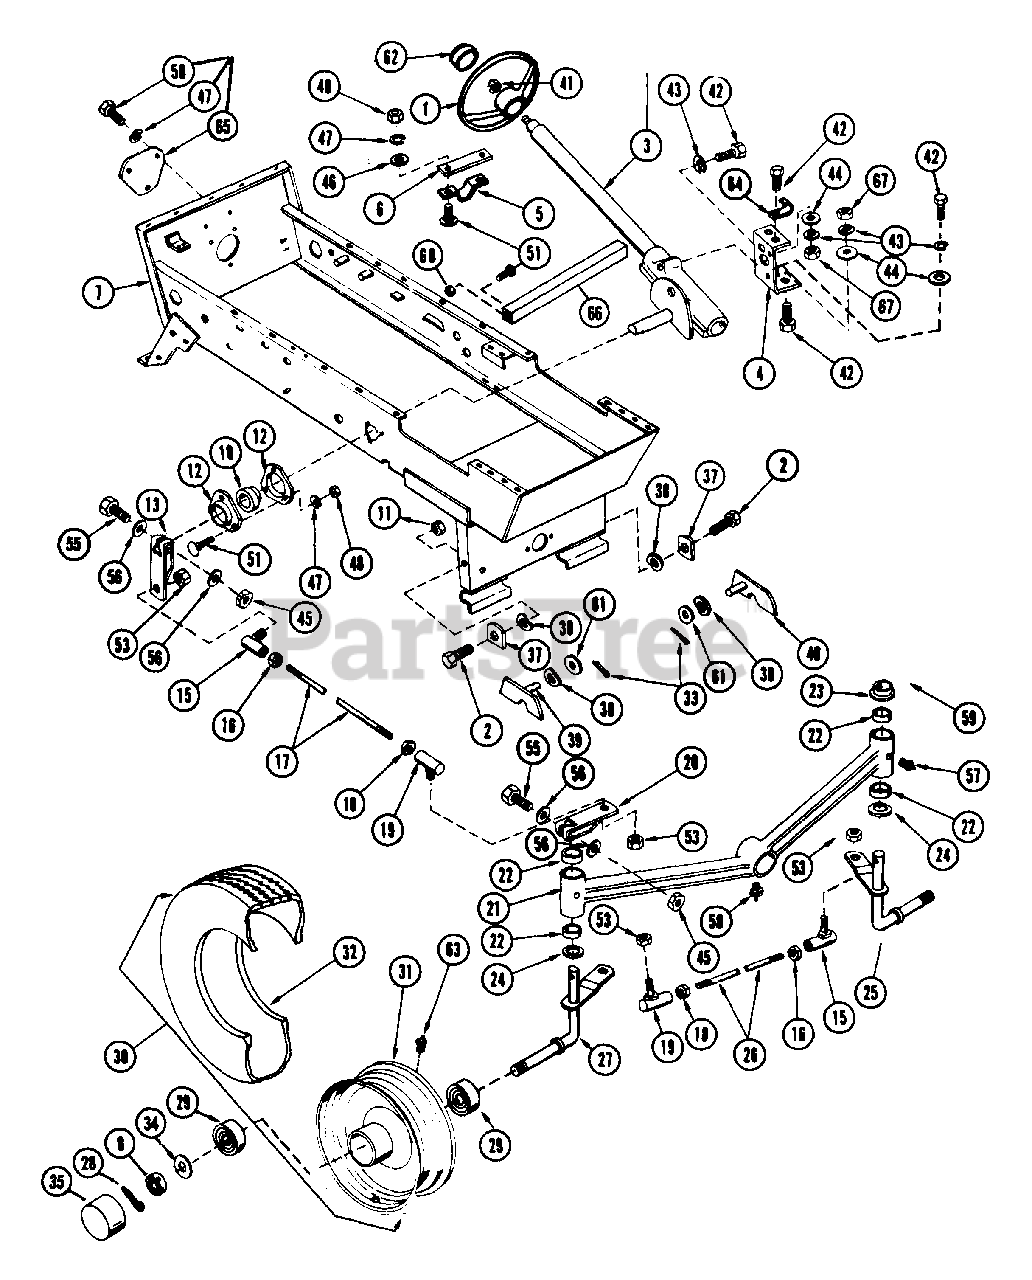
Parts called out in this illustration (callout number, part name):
1	STEERING WHEEL
2	BLT-HEX .38-16X1.00 PL
3	STEERING GEAR ASSY
4	MOUNTING BRACKET
5	STEERING COLUMN CLAMP
7	MAIN FRAME ASSY HYDRO
7	MAIN FRAME ASSEMBLY - TWIN
7	MAIN FRAME ASSY 10G
7	MAIN FRAME ASSY 14G
8	NUT-SL 1.0-14
10	BRG-BALL 1.0X2.047X1.20
11	NUT-LK-CTR .375-16 GR A PL
12	BEARING FLANGE
13	STEERING ARM
15	BALL JOINT L.H.
16	NUT-JAM .50-20 LH THD PL
17	DRAG LINK
18	NUT-JAM .50-20 PL
19	BALL JOINT R.H.
20	FRONT STEERING ARM
21	FRT AXLE
22	BSHG-SLV 1.000X1.125X.875
23	SPINDLE CAP
24	PLASTIC WASHER
25	L.H. SPINDLE
26	TIE ROD
27	R.H. SPINDLE
28	PIN-COTR .18X1.25 PL
29	BRG-BALL 1.0X2.0X.55
30	FRONT TIRE ASSEMBLY
32	TIRE 16X6.50-8 2 PLY
33	PIN-COTR .12X.75 PL
34	WSHR-FL-STL 1.015X1.500X.125
35	FRONT HUB CAP
37	LOCK STOP
38	SPRING WASHER
39	LATCH R. H.
40	LATCH L. H.
41	NUT-LK-JAM .625-18 YWZC
42	BLT-HEX .38-16X1.00 PL GR5
43	WSHR-LK .375X.094 MED PL
44	WSHR-FL-STL .438X1.0X.083 PL
45	NUT-LK-CROWN .50-13 GR C PL
46	WSHR-FL-STL .38X.875X.083 PL
47	WSHR-LK .312X.097 PL HVY
48	NUT-HEX .312-18
50	BLT-HEX .31-18X.75 PL GR2
51	BLT-RDHDSQNK .31-18X1.00 PL
53	NUT-LK .50-20 PL
55	BLT-HEX .50-13X2.50 PL GR5
56	WSHR-FL-STL .531X.938X.104 PL
57	SPIN DRIVE ZERK FITTING
58	ZERK FITTING
59	PIN-ROLL .250X1.75
61	WSHR-FL-STL.406X.812X.065PL
62	STEERING WHEEL CAP
63	ZERK FITTING
64	J-CLAMP
66	BRACE
67	NUT-HEX .375-16
68	NUT-LK .312-18 GR A PL
